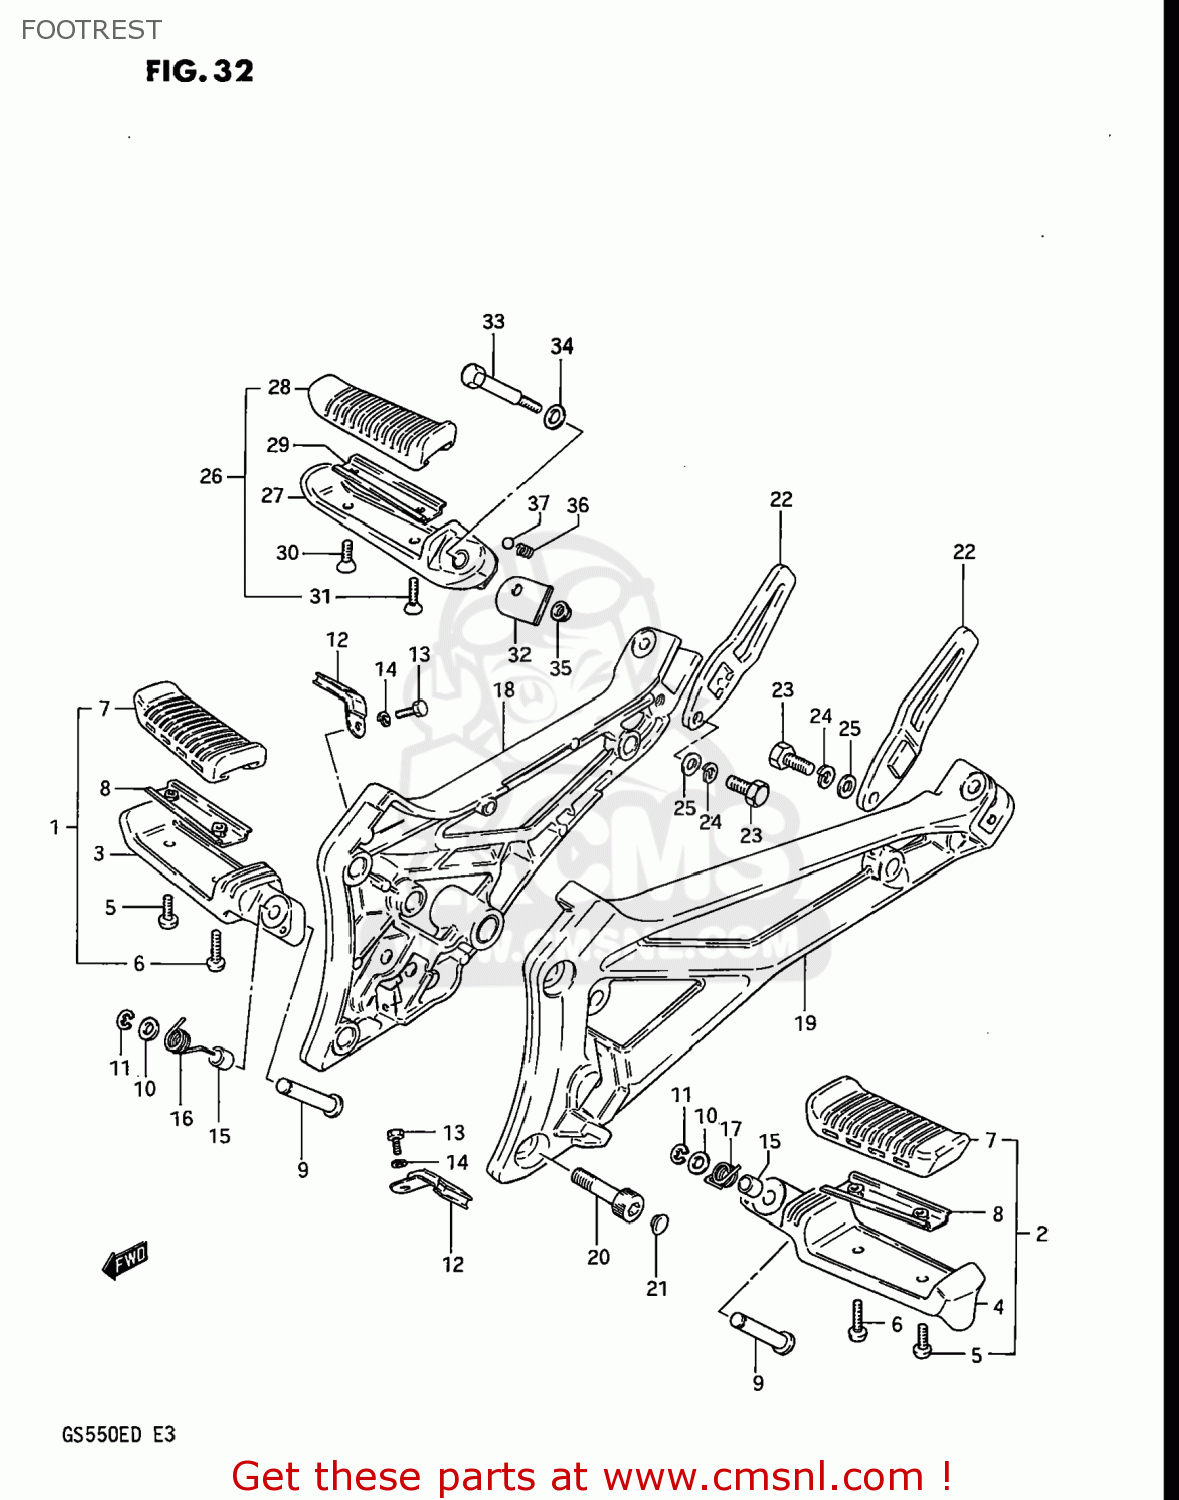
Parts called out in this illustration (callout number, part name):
1	FOOTREST ASSEMBLY,FRONT,RIGHT
2	FOOTREST ASSEMBLY,FRONT,LEFT
3	BAR,FRONT FOOTREST
4	FOOTREST,FRONT,LEFT
5	SCREW
6	SCREW
7	RUBBER,FOOTREST
8	PLATE,FR FOOTREST RUBBER
9	PIN
10	WASHER
11	E RING 6MM
12	CUSHION,FR FOOTREST
13	BOLT
14	LOCK WASHER
15	BUSHING
16	SPRING
17	SPRING
18	BRACKET
19	BRACKET
20	BOLT 10X27
21	CAP
22	GUARD,REAR FOOT
23	BOLT
24	LOCK WASHER
25	WASHER
26	FOOTREST ASSY,PILLION,R
27	BAR,PILLION FOOTREST,LEFT
28	RUBBER,PILLION FOOTREST
29	PLATE,RUBBER STOPPER
30	SCREW 5X12
31	SCREW
32	PLATE,SPRING STOP,R
33	BOLT
34	WASHER
35	NUT
36	SPRING
37	BALL
